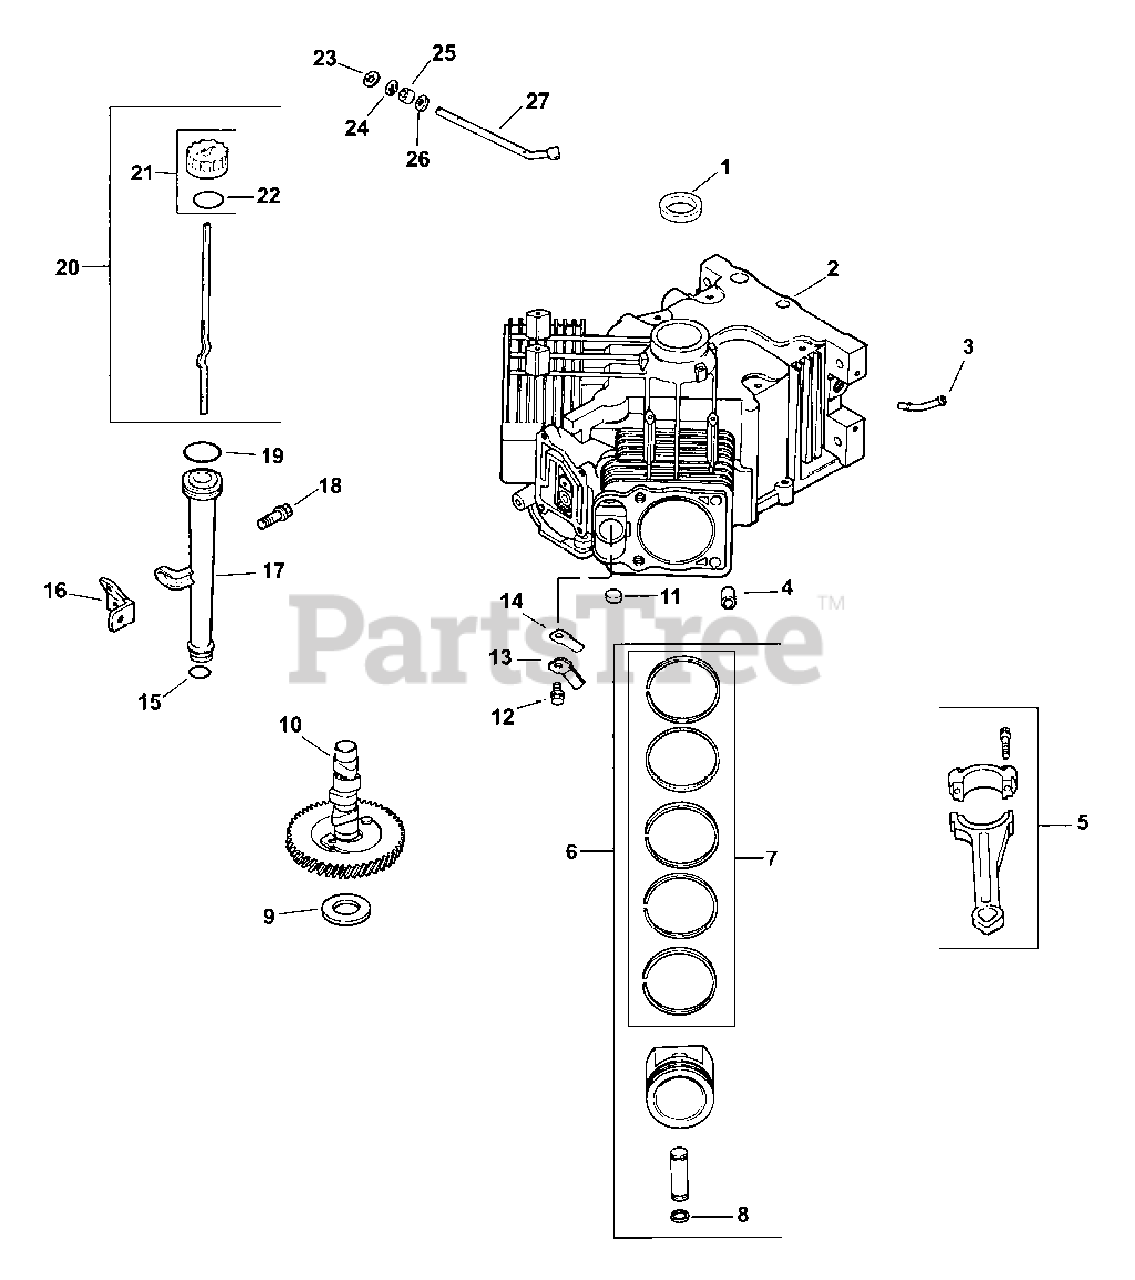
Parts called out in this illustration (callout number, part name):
1	Seal, Front Oil
4	Locating Pin
5	Connecting Rod (Std.)
5	Connecting Rod (.025)
6	Piston w/Ring Set (Std.)
6	Piston w/Ring Set (.080)
7	Ring Set (Std. & .080)
8	Piston Pin Retainer
9	Camshaft Shim-Red
9	Camshaft Shim-Black
9	Camshaft Shim-White
9	Camshaft Shim-Blue
9	Camshaft Shim-Yellow
9	Camshaft Shim-Green
9	Camshaft Shim-Gray
10	Camshaft
11	Cup Plug
12	Hex Flange Screw M5 x .8 x 10
13	Reed Retainer
14	Breather Reed
16	Bracket
17	Oil Fill Tube
18	Hex Flange Screw M5 x .8 x 16
20	Dipstick Assembly
21	Oil Fill Cap Kit
22	Dipstick O-Ring
23	Retainer Ring
24	Plain Washer 9mm
25	Governor Cross Shaft Seal
26	Plain Washer 1/4"
27	Governor Cross Shaft
